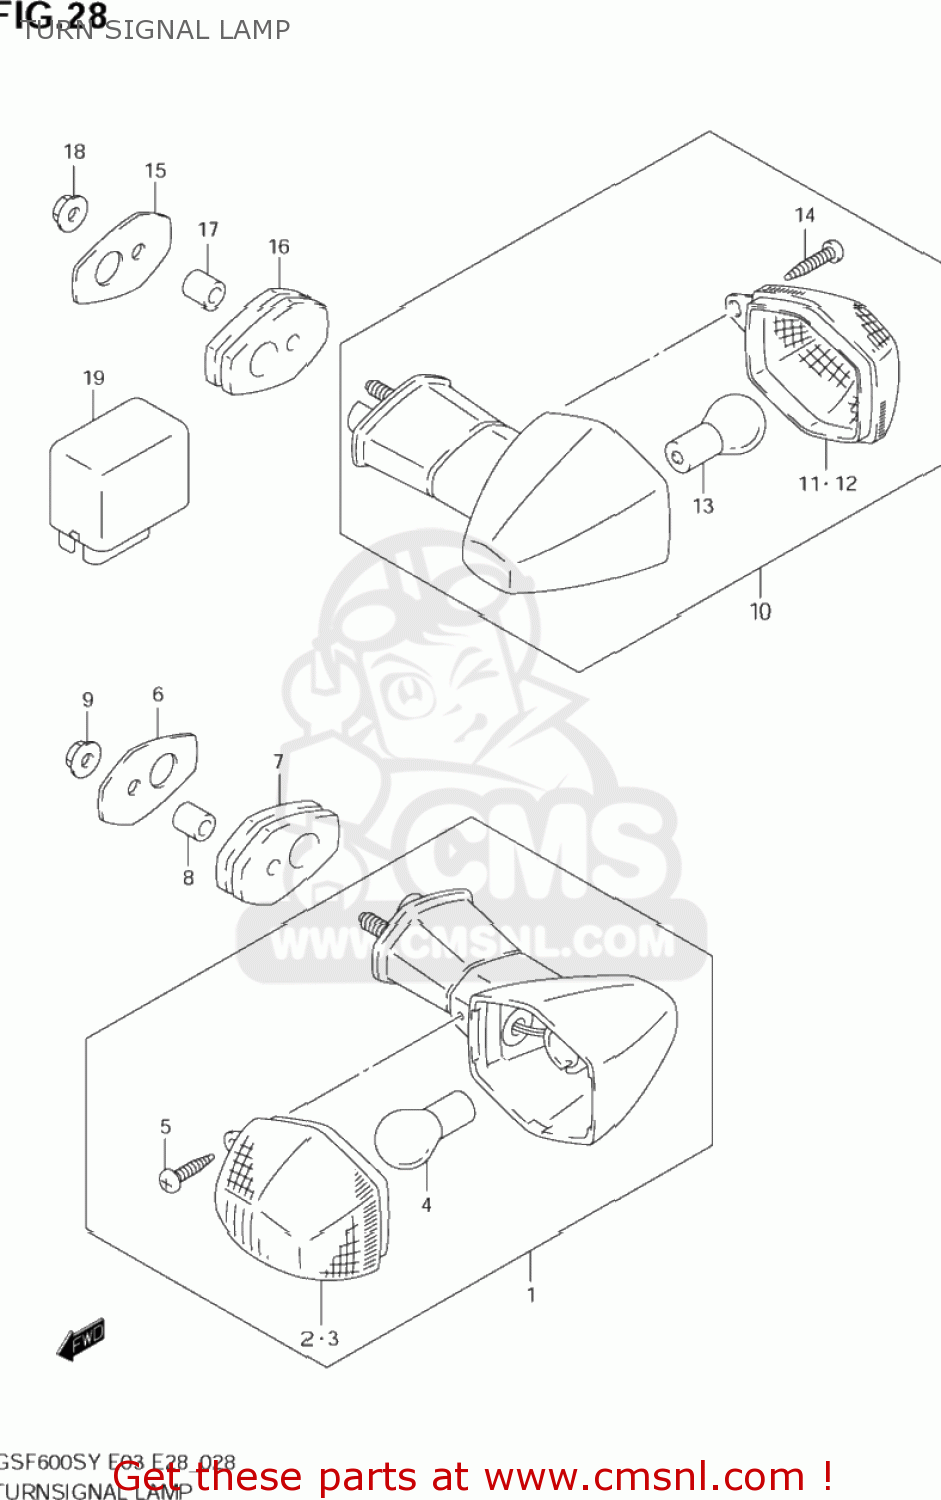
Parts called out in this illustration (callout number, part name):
1	LAMP ASSY,FR TURN SIGNAL,R
2	LENS
3	LENS
4	BULB(12V21W)
5	SCREW
6	PLATE,FR TURNSIGNAL
7	CUSHION,FR TURNSIGNAL
8	SPACER(5.5X9.5X10)
9	NUT
10	LAMP ASSY,RR TURNSIGNAL,R
11	LENS
12	LENS
13	BULB(12V21W)
14	SCREW
15	PLATE,FR TURNSIGNAL
16	CUSHION,FR TURNSIGNAL
17	SPACER(5.5X9.5X10)
18	NUT
19	RELAY ASSY,TURNSIGNAL LAMP
